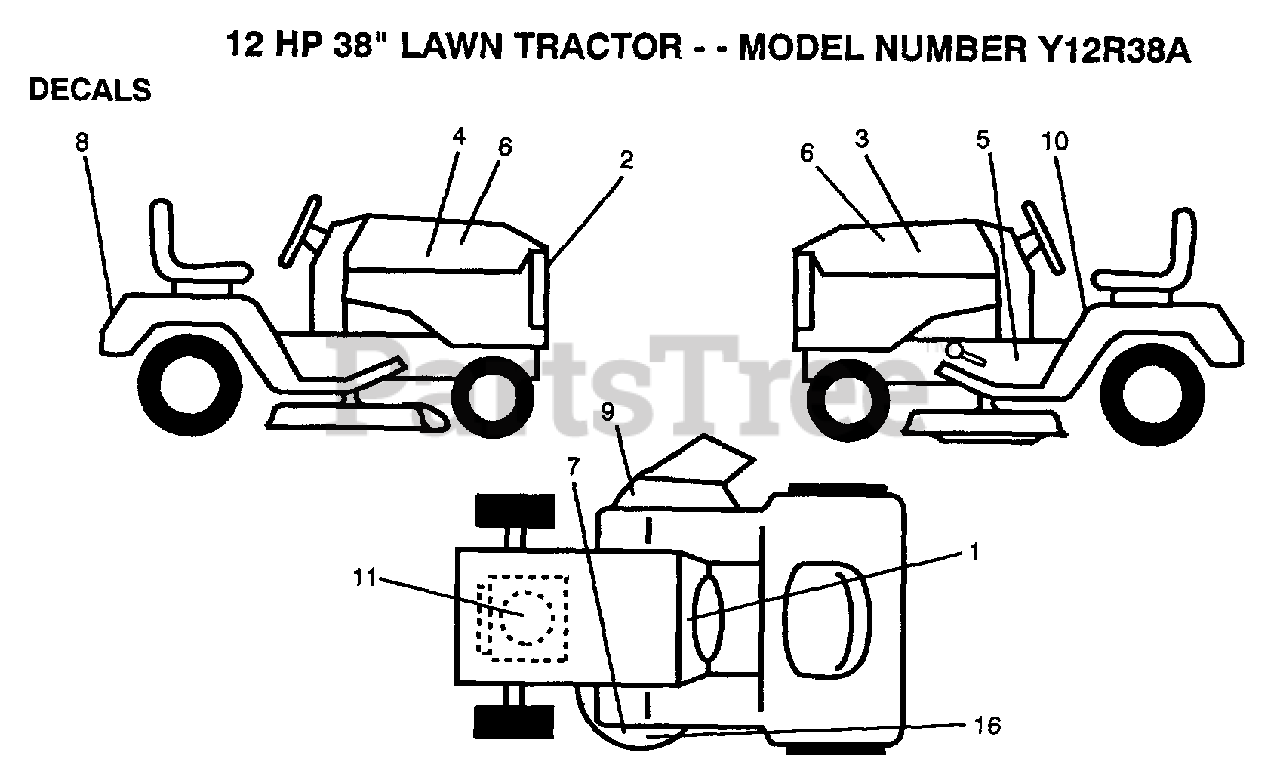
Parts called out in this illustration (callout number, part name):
2	"DECAL,LIGHT BOX"
5	IND HGT DECK DECA
7	DECAL YT
9	DECAL WARNING
10	DECAL CAUTION
11	DECAL.ENG.271967
16	"DECAL,ENVIRO DECK"
